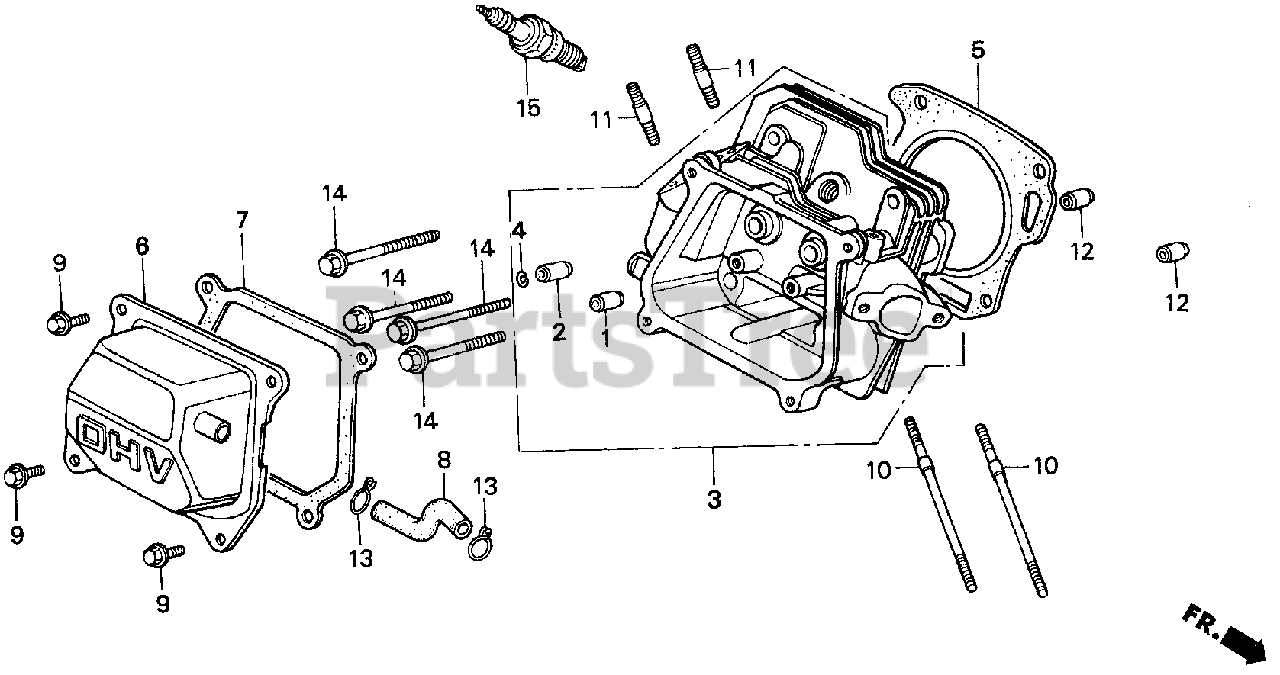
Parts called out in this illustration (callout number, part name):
1	GUIDE, VALVE (OS)
2	GUIDE, EX. VALVE (OS)
3	CYLINDER HEAD
4	CLIP, VALVE GUIDE
5	GASKET, CYLINDER HEAD
6	COVER, HEAD (BREATHER TUBE)
7	GASKET, CYLINDER HEAD COVER
8	TUBE, BREATHER
9	BOLT, FLANGE (6X12) (CT200)
10	BOLT, STUD (6X109)
11	BOLT, STUD (8X32)
12	PIN A, DOWEL (10X16)
13	CLIP, TUBE (C12)
14	BOLT, FLANGE (8X60)
15	SPARK PLUG (BPR5ES) (NGK)
15	SPARK PLUG (W16EPR-U) (DENSO)
15	SPARK PLUG (BPR6ES) (NGK)
15	SPARK PLUG (W20EPR-U) (DENSO)
